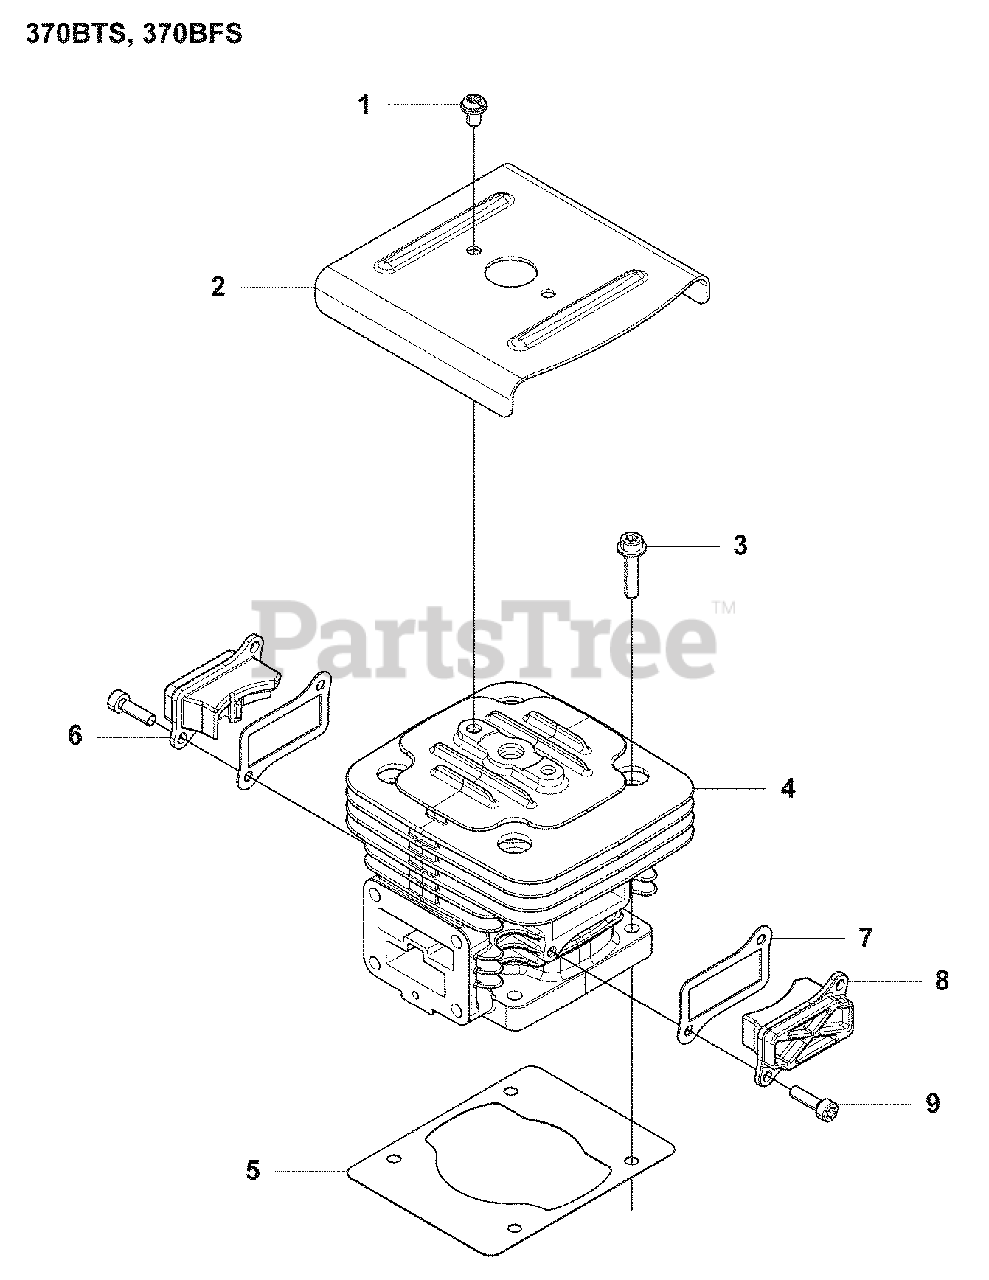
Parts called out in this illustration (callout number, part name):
2	Plate
3	Torx Bolt
5	Gasket
6	Cover, TR F
7	Gasket
8	Cover, Tr-S
9	Torx Bolt, M4 X L16
